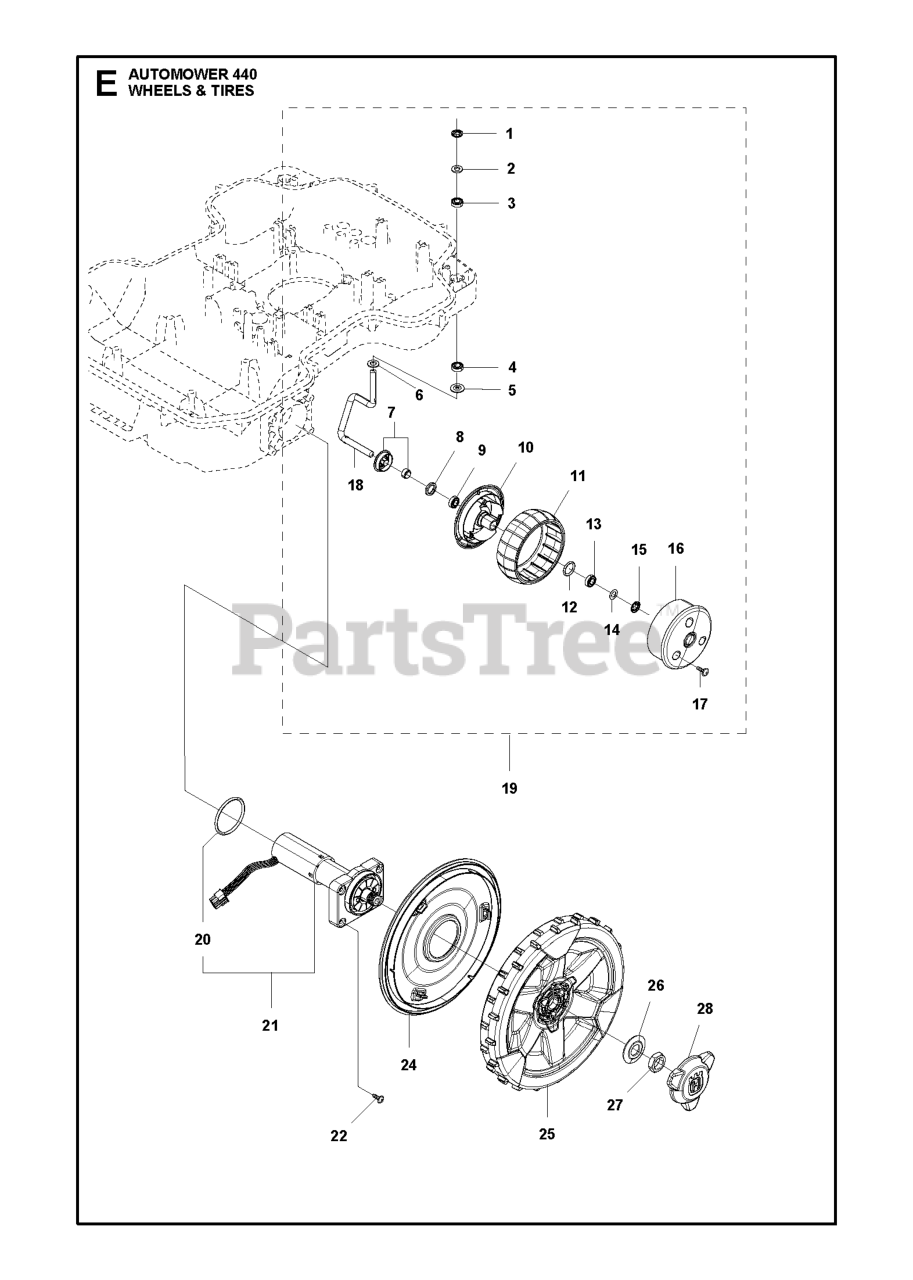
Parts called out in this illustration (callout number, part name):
1	LOCKWASHER PUSH-ON TYPE P 8 BV
2	WASHER DIN 988 13X8X0.5
3	BALL BEARING SINGLE ROW S688
4	BALL BEARING SINGLE ROW S688
5	WASHER FRONT WHEEL CENTER HOLE
6	WASHER DIN 988 13X8X0.5
7	SHIELD KIT
8	SEALING 12X18X3
9	BALL BEARING SINGLE ROW S688
10	WHEEL FRONT WHEEL INSIDE
11	WHEEL RUBBER TYRE
12	O-RING 2,62X15,54
13	BALL BEARING SINGLE ROW S688
14	WASHER DIN 988 13X8X0.5
15	LOCKWASHER PUSH-ON TYPE P 8 BV
16	WHEEL FRONT WHEEL OUTSIDE
17	SCREW 14MM
18	SPINDLE SPINDLE FRONT WHEEL RI
19	WHEEL KIT FRONT
20	O-RING LIGHT GREY
21	MOTOR KIT DRIVE WHEEL
22	SCREW ITXPANT
24	COVER REAR WHEEL
25	Wheels
26	WASHER WASHER REAR WHEEL 16X40
27	HEXAGON THIN NUT
28	HUB CAP REAR WHEEL NO CENTER P
